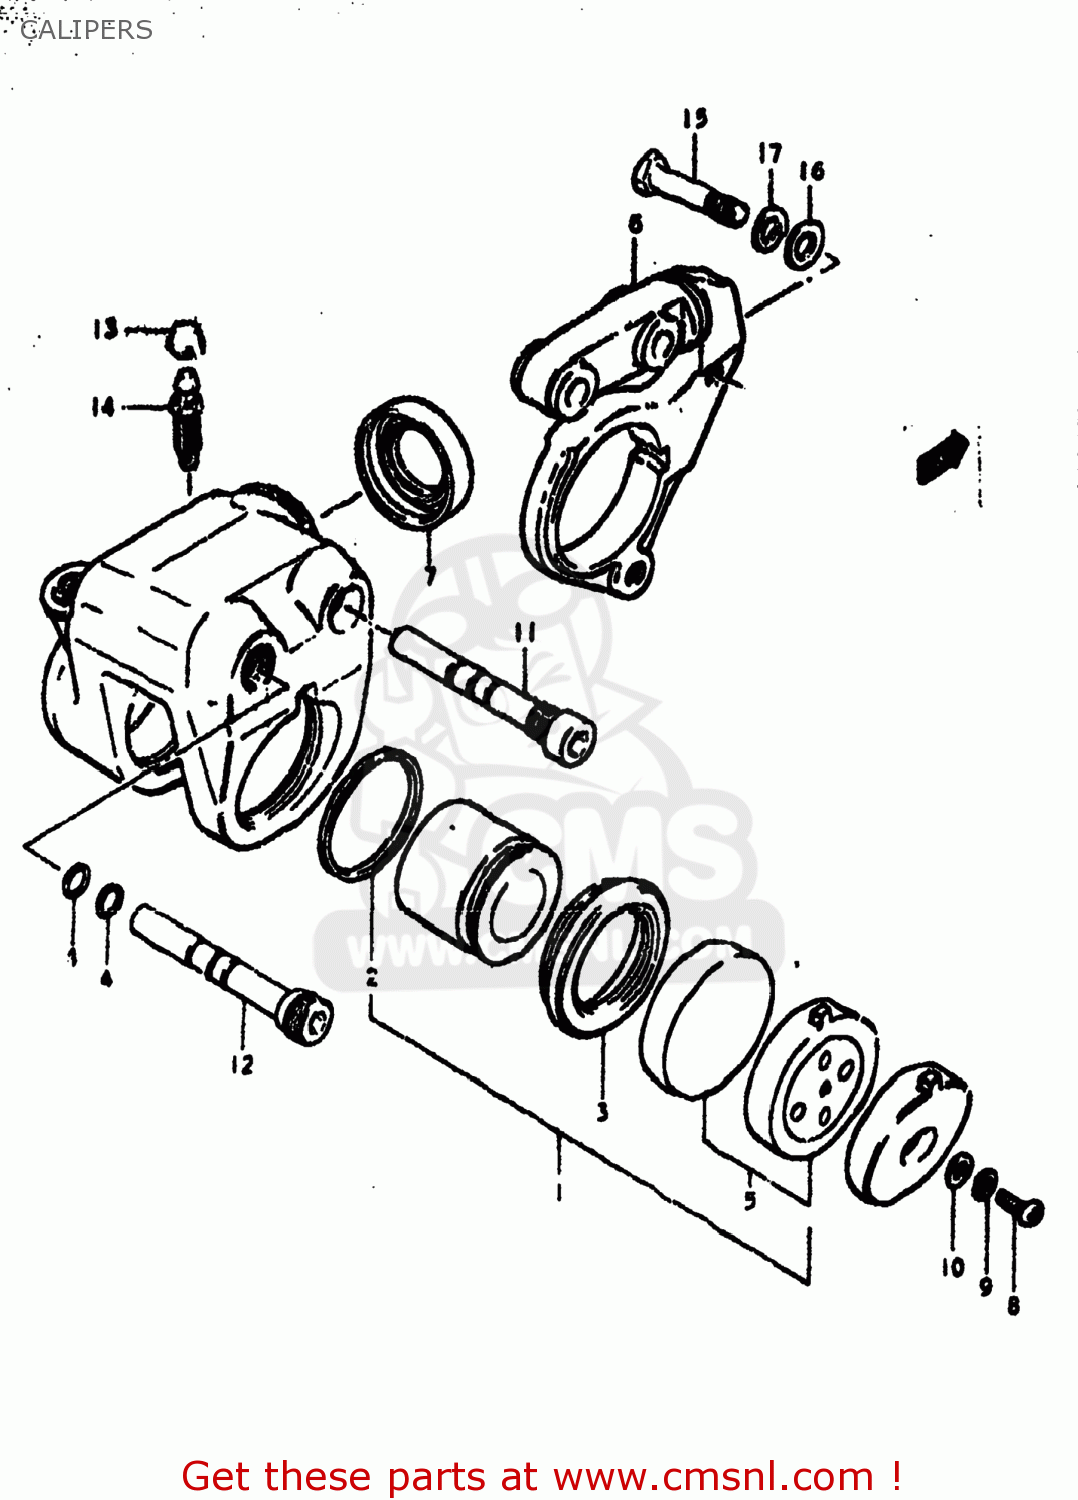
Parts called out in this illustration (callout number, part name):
0	CALIPER ASSEMBLY,FRONT,LEFT
1	PAD SET
2	SEAL,PISTON
3	BOOT,PISTON
4	O RING,AXLE CALIPER
5	PAD SET (NAS)
6	HOLDER,CALIPER
7	BOOT,HOLDER
8	SCREW
9	LOCK WASHER
10	WASHER
11	AXLE,CALIPER
12	AXLE NO.2
13	CAP,BLEEDER PL
14	BLEEDER
15	BOLT
16	WASHER
17	LOCK WASHER
